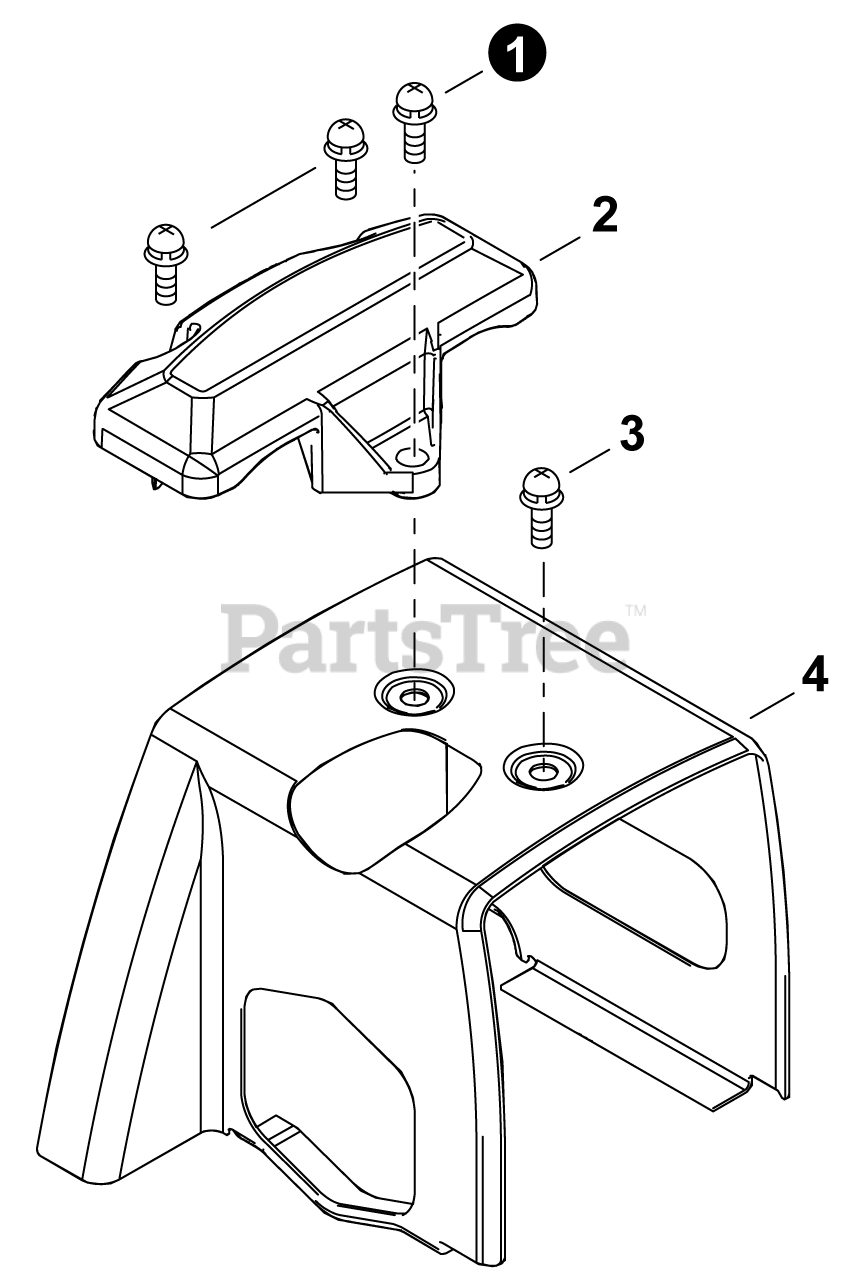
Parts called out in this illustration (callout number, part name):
1	SCREW 5x14
2	GUARD, TOP
3	SCREW 5x10
4	COVER, ENGINE
